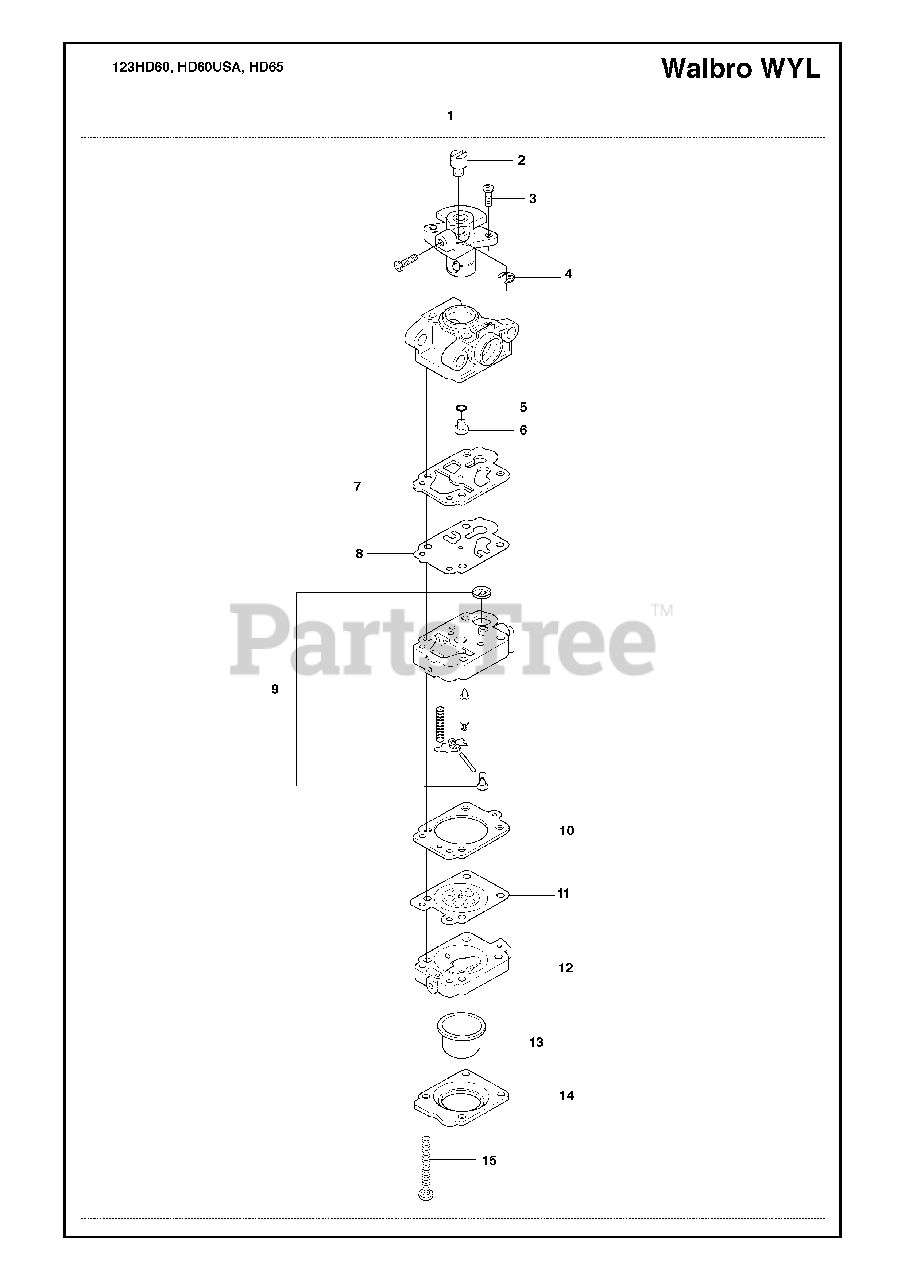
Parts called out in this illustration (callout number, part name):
1	Carburetor
2	CONNECTION
3	SCREW
4	Retaining Ring
7	Gasket
8	GASKET
13	Primer Bulb
14	PUMP COVER
